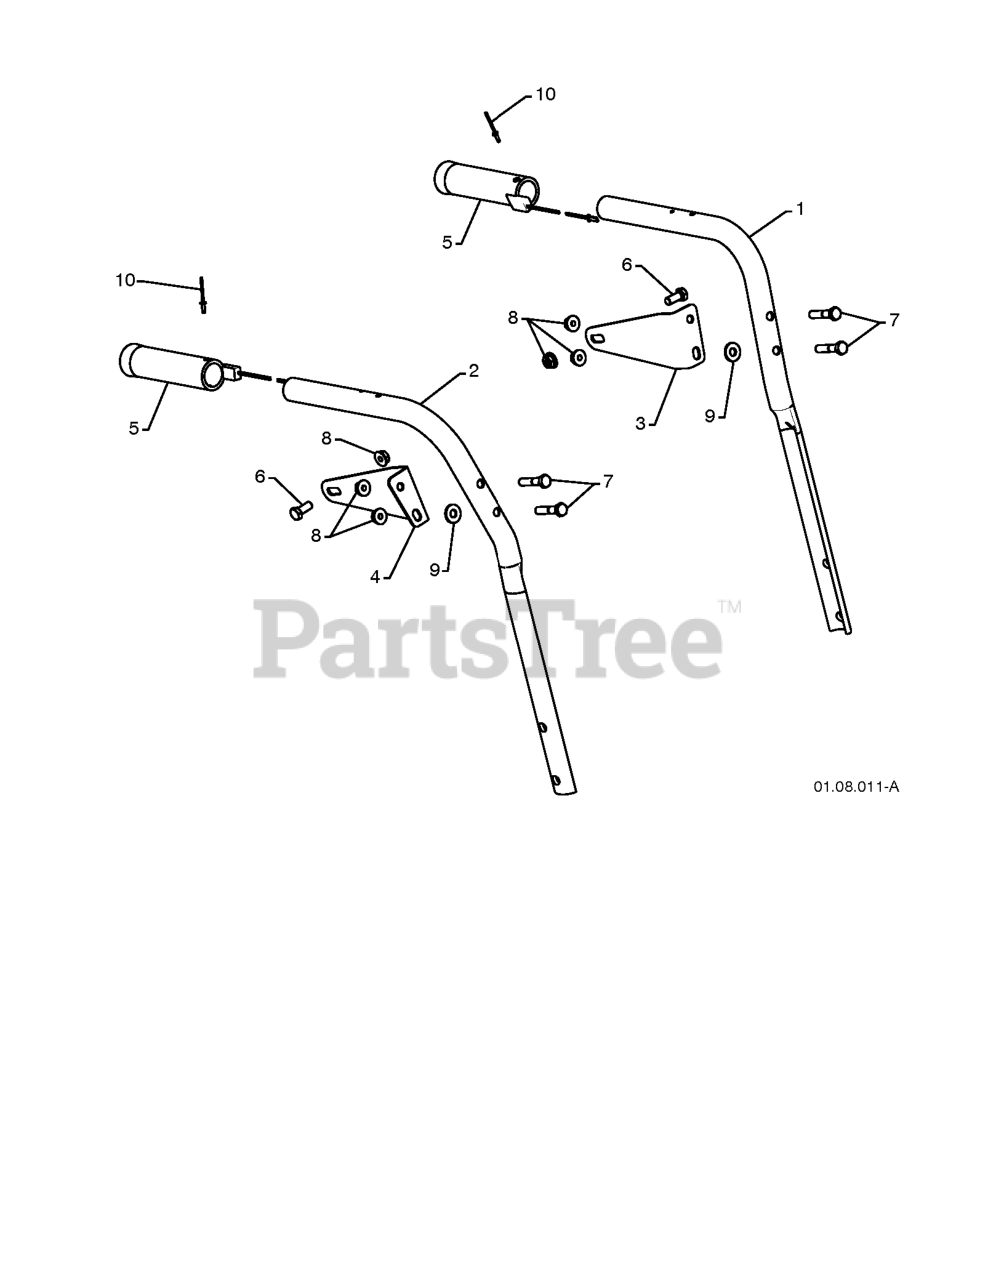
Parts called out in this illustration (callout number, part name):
1	TUBE.HANDLE.PLOW.LH.GREY
2	TUBE.HANDLE.PLOW.RH.GREY
3	BRKT.PANEL.LH.INT
4	BRKT.PANEL.RH.INT
5	GRIP.HANDLE.HEATED
6	BOLT.FIN.HEX.5/16-18X3/4
7	HEX BOLT
8	NUT.LOCK.5/16-18
9	WASHER.20X8.5
10	RIVET.POP.1/8X
